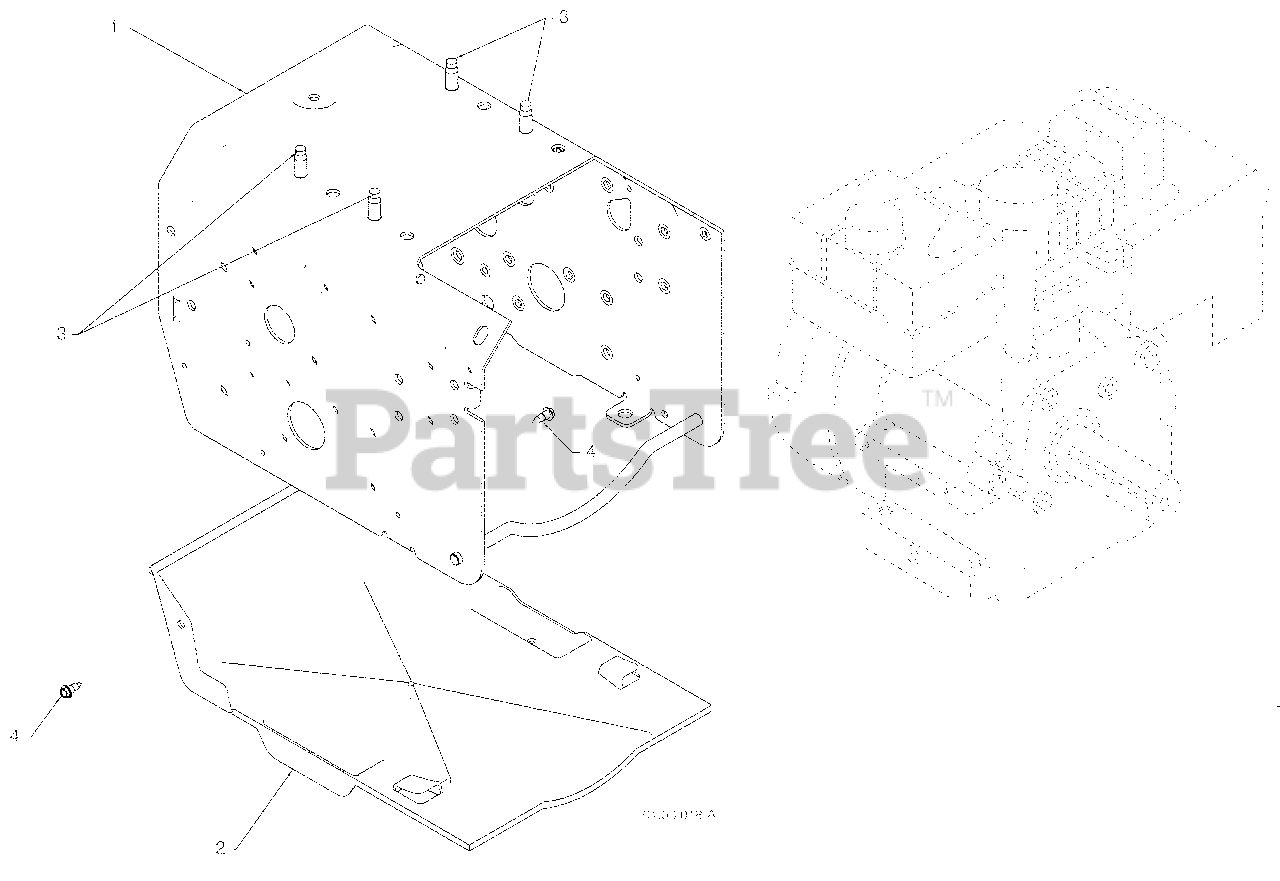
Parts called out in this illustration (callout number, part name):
2	BOTTOM PAN
3	BOLT 3/8-16
4	SCREW 10-24 X .625
